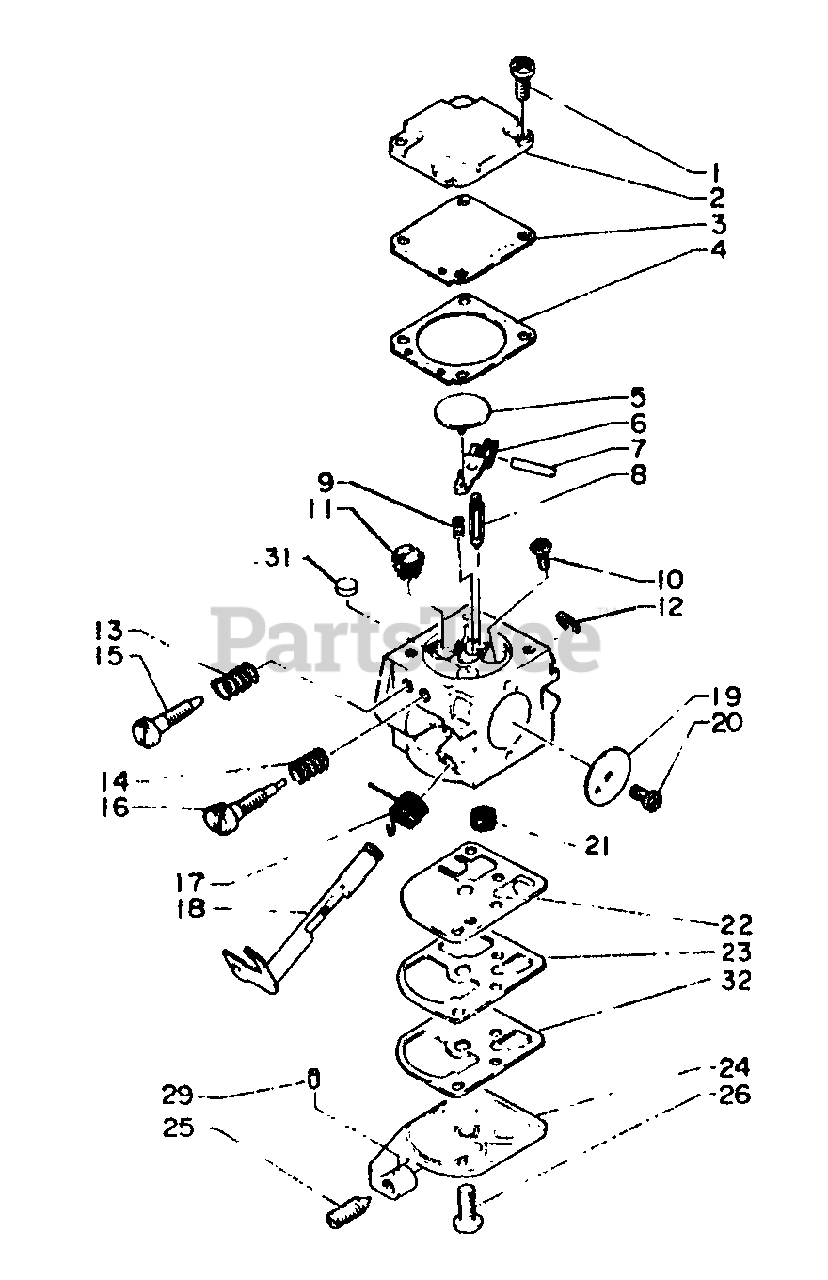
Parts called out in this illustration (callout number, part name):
1	SCREW
2	COVER, DIAPHRAGM
3	DIAPHRAGM, METERING
4	GASKET, DIAPHRAGM
5	DISK
6	LEVER, METERING
7	PIN, METERING LEVER
8	VALVE, INLET NEEDLE
9	SPRING, COIL
11	NOZZLE, CHECK VALVE
15	NEEDLE, HIGH SPEED
16	NEEDLE, IDLE
17	SPRING, THROTTLE RETURN
18	SHAFT, THROTTLE
19	VALVE, THROTTLE
21	STRAINER
22	DIAPHRAGM, PUMP
23	GASKET, PUMP
24	BASE, PUMP
25	SCREW, IDLE ADJUST
29	PIECE, FRICTION
31	PLUG, WELCH
32	DIAPHRAGM, SURGE
